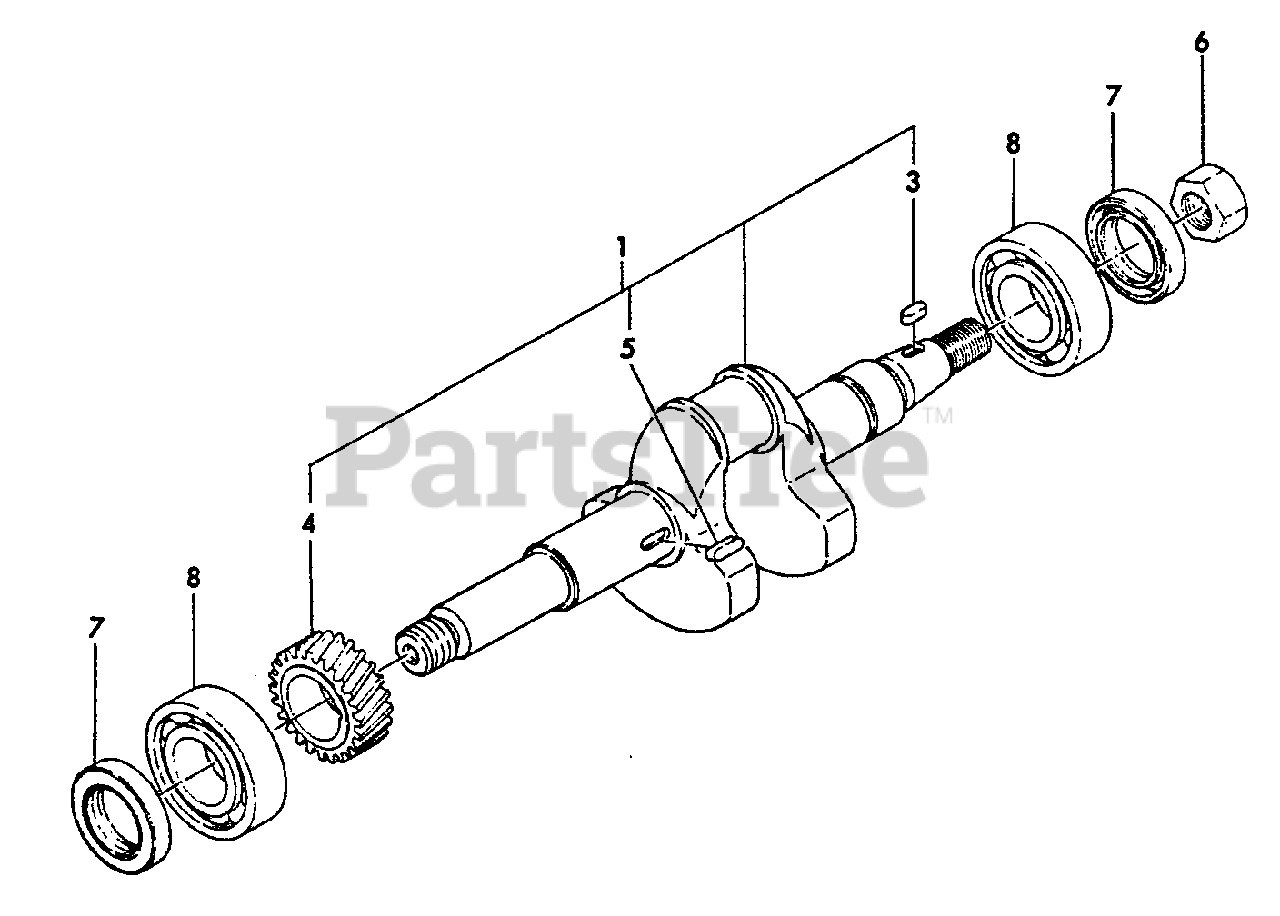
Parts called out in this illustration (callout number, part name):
1	CRANKSHAFT ASSY
3	KEY - 4×10
4	GEAR, CRANKSHAFT
5	KEY 4×12
6	NUT - 14
7	SEAL, OIL
8	BEARING, BALL
